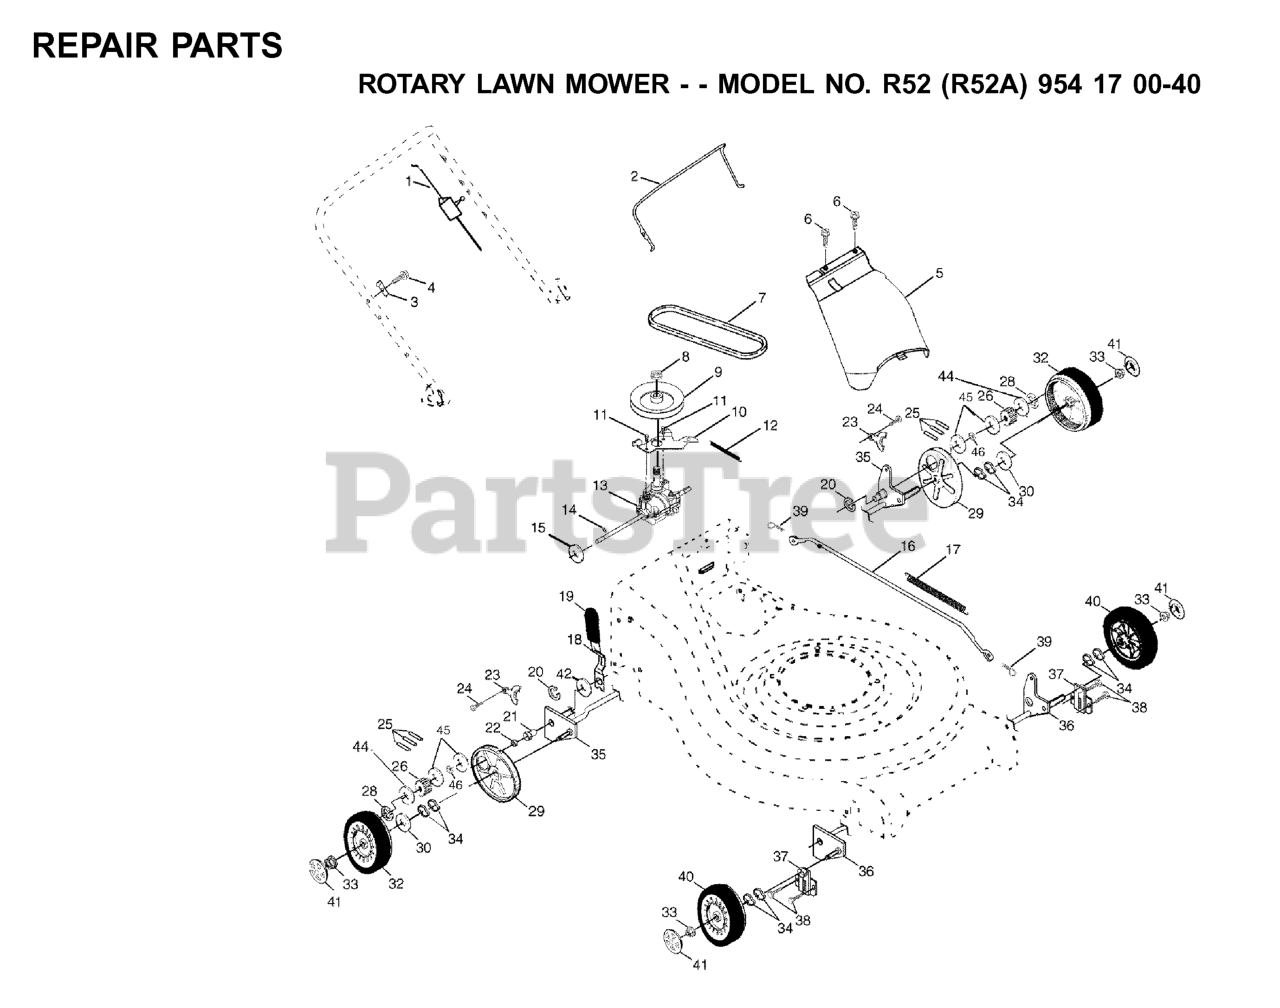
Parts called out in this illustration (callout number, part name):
1	CABLE.DRIVE.21.RWGD.
2	BAIL.CONT.DR.21.RWGD.BLACK
3	DOWNSTOP BRACKET
4	SCREW.HEX.HEAD.WASHER.10-16
5	DRIVE COVER
8	FLANGED LOCKNUT 3/8-16 ZINC
10	BELT GUIDE
11	Screw, Hex Washer Head #10-24 x .668
13	TRANSMISSION ASM. (WALK)
14	PIN.SPRING.THRUST
15	THRUST WASHER
16	ROD CONNECTING
17	SPRING
18	SPRING
19	KNOB
21	RP BEARING SUPPORT
22	BEARING, BALL
23	BRACKET
25	PAWL.DRIVE.ETCHED
26	PINION.DRIVE.WALK
28	E-RING 7/16 RE
29	DUST SHROUD PM
30	WASHER FLUT
33	HEX FLANGE LOCKNT
34	WAVE WASHER
35	SHAFT ASSY
36	SHAFT ASSY
37	RETAINER.FRONT.SHAFT
39	RETAINER CLIP
40	WHEEL ASMBLY FRONT
41	CAP.HUB.ARC.SPOKE.8".LP
42	WASHER.ZINC.PLATED
45	WASHER.BELLEVILLE (3 2 LB)
